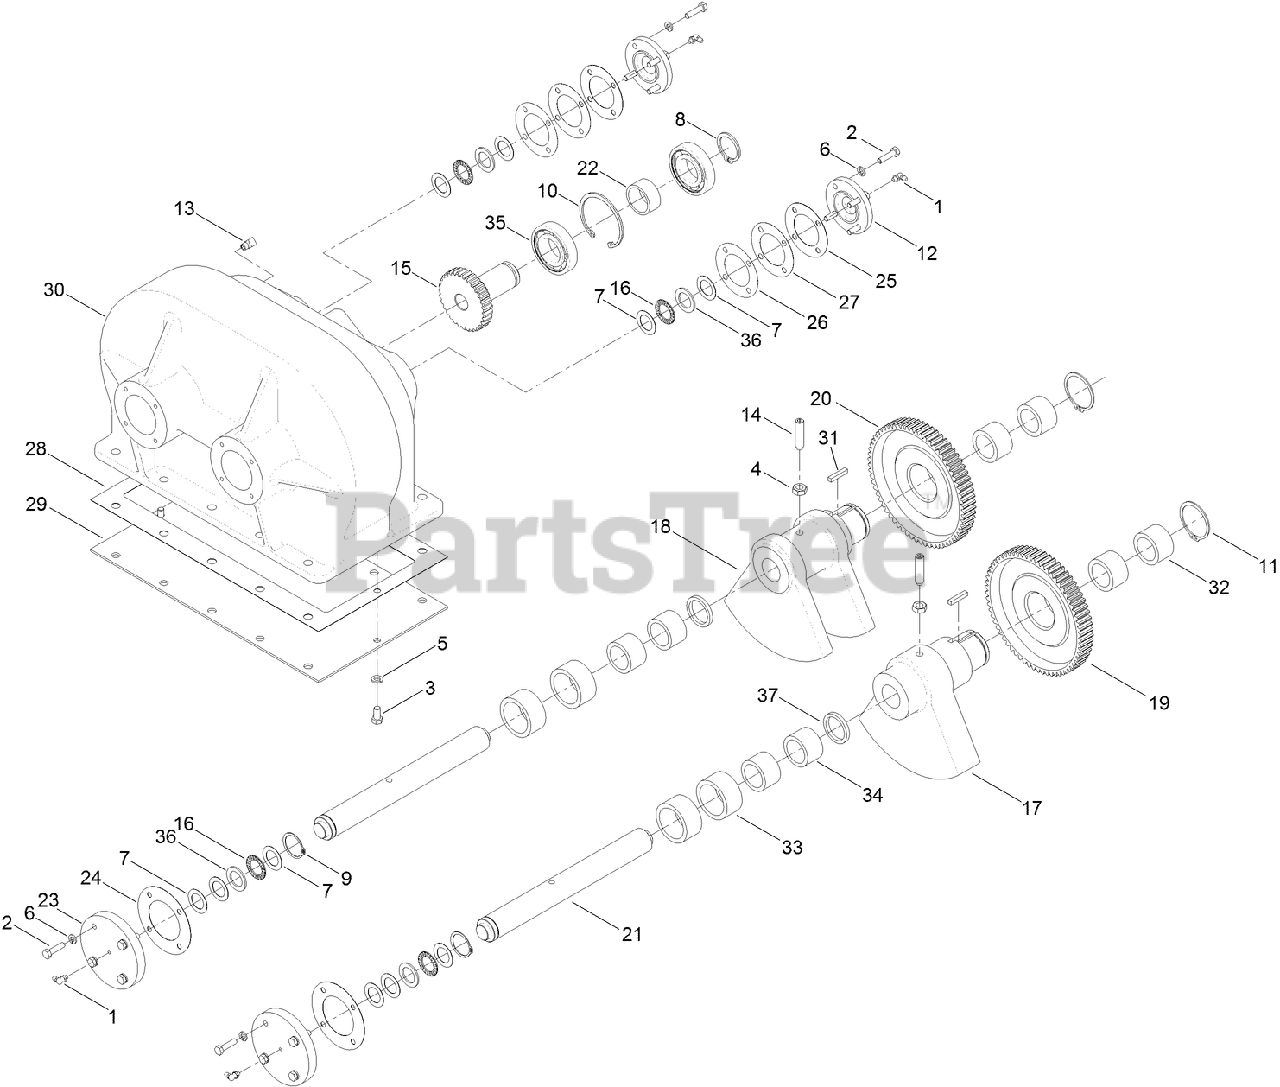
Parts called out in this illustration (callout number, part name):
1	FITTING-GREASE, 90 DEG
2	SCREW-HH
3	SCREW-HH
4	NUT-JAM
5	WASHER-LOCK
6	WASHER-LOCK
7	WASHER-THRUST
8	RING-RETAINING, EXTERNAL
9	RING-RETAINING, EXTERNAL
10	RING-RETAINING, INTERNAL
11	RING-RETAINING
12	CAP-BEARING
13	FITTING-ELBOW, 90
14	SCREW-SET, HSH
15	GEAR-DRIVE, PLOW
16	BEARING
17	WEIGHT-COUNTER
18	WEIGHT-COUNTER
21	SHAFT-BEARING
23	CAP-BEARING
26	GASKET-SHIM
27	GASKET-SHIM
28	GASKET-GEARCASE
29	PLATE-COVER
30	HOUSING-gearbox
31	KEY-SQUARE
32	BEARING
33	BEARING
34	BEARING
35	BEARING
36	WASHER-THRUST
